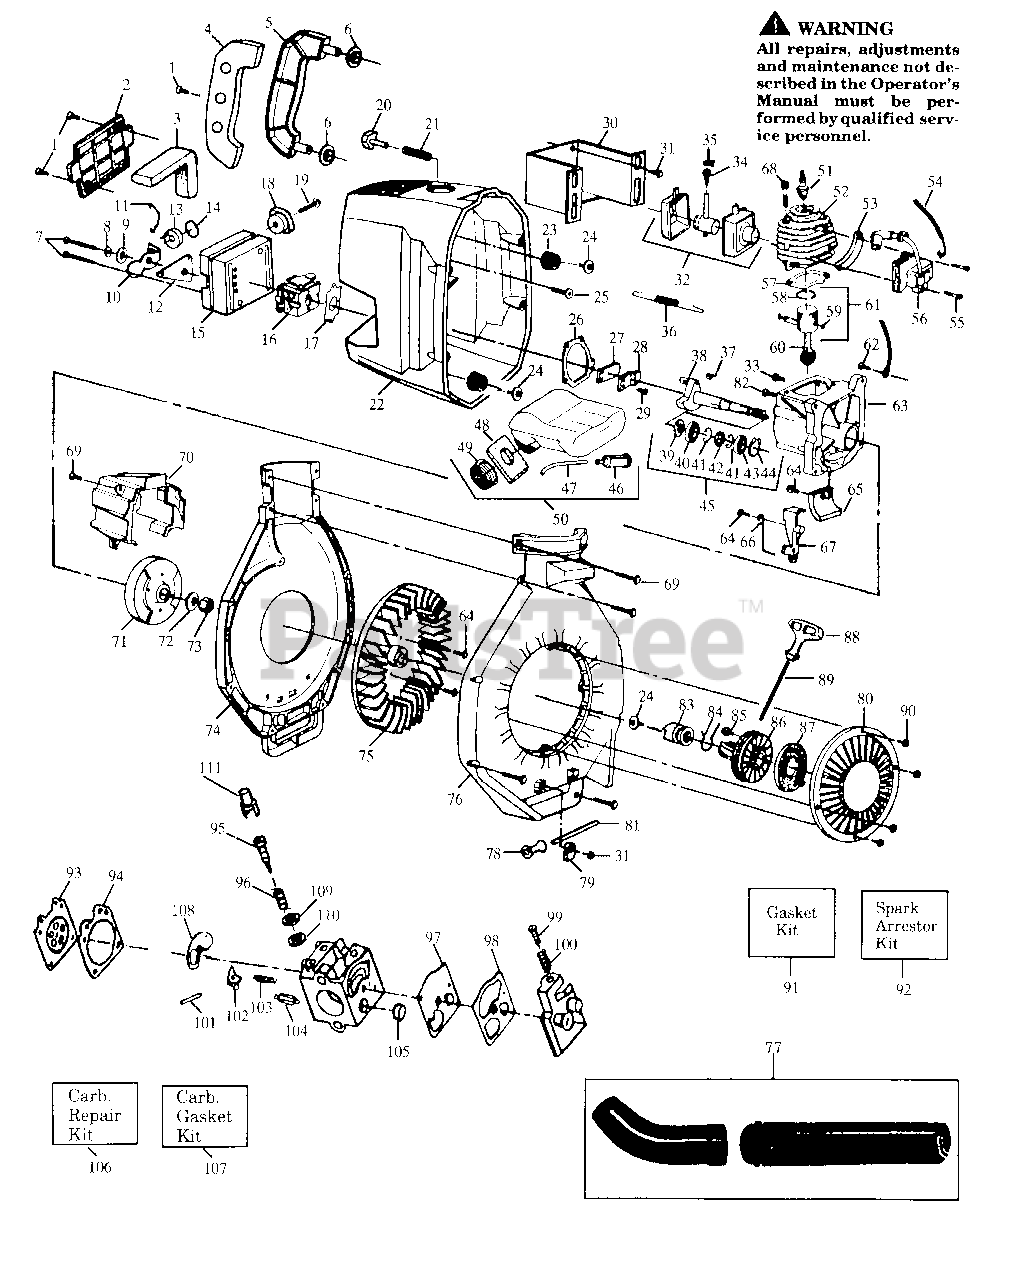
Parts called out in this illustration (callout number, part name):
2	Air Filter Cover
3	Air Filter
4	Handle Cover
6	Handle Isolator
8	Choke Spacer
9	Wave Washer
10	Choke Shutter
11	Throttle Wire
12	Choke Mtg. Plate
13	Retainer
14	Wave Washer (Knob)
16	Type 1 (WA-207A)
16	Type 2 (WA-217, w/ Limiter Cap, # 111)
17	Carburetor Gasket
18	Throttle Knob
27	Reed Valve
28	Reed Stop
30	Heat Shield
31	Screw
34	Spark Arrestor Screen
35	Spark Arrestor Clamp
36	Muffler Spring
38	Crankshaft Ass'y.See Service Ref. 1
40	Inner Bearing
42	Crankshaft Seal
43	Outer Bearing
44	Retaining Ring
45	Crankcase/Crankshaft Ass'y.
46	Fuel Pick-Up Ass'y.
47	Fuel Line Kit
49	Fuel Cap
50	Fuel Tank Ass'y.
51	Spark Plug (CJ-8Y)
52	Cylinder
54	Leadwire Switch
56	Ignition Module
57	Gasket
58	Piston Ring
59	Retainer
60	Piston Rod
61	Piston Kit (Inc. 58,59, Pin)
63	Crankcase Ass'y
65	Isolator
67	Insulator
69	Screw
71	Flywheel
74	Blower Housing (Upper)
75	Impeller
76	Blower Housing (Lower)
77	Blower Tube Kit
79	Retainer
80	Pulley Housing
81	Roll Pin
84	Drag Element
86	Starter Pulley
87	Starter Spring
88	Starter Handle
89	Rope Kit
91	Gasket Kit
92	Spark Arrestor Kit
93	Metering Diaphragm
94	Metering Diaphragm Gasket
95	Mixture Needle
96	Mixture Needle Spring
97	Fuel Pump Diaphragm
98	Fuel Pump Gasket
99	Idle Speed Screw
100	Idle Speed Spring
101	Metering Lever Pin
102	Metering Lever
103	Metering Lever Spring
104	Inlet Needle Valve
105	Fuel Inlet Screen
106	Carb. Kwik Repair Kit
107	Carb. Gasket/Diaphragm Kit
108	Circuit Plate Gasket
109	Mixture Needle Washer
110	"O" Ring Mixture
111	Limiter Cap (Black)
